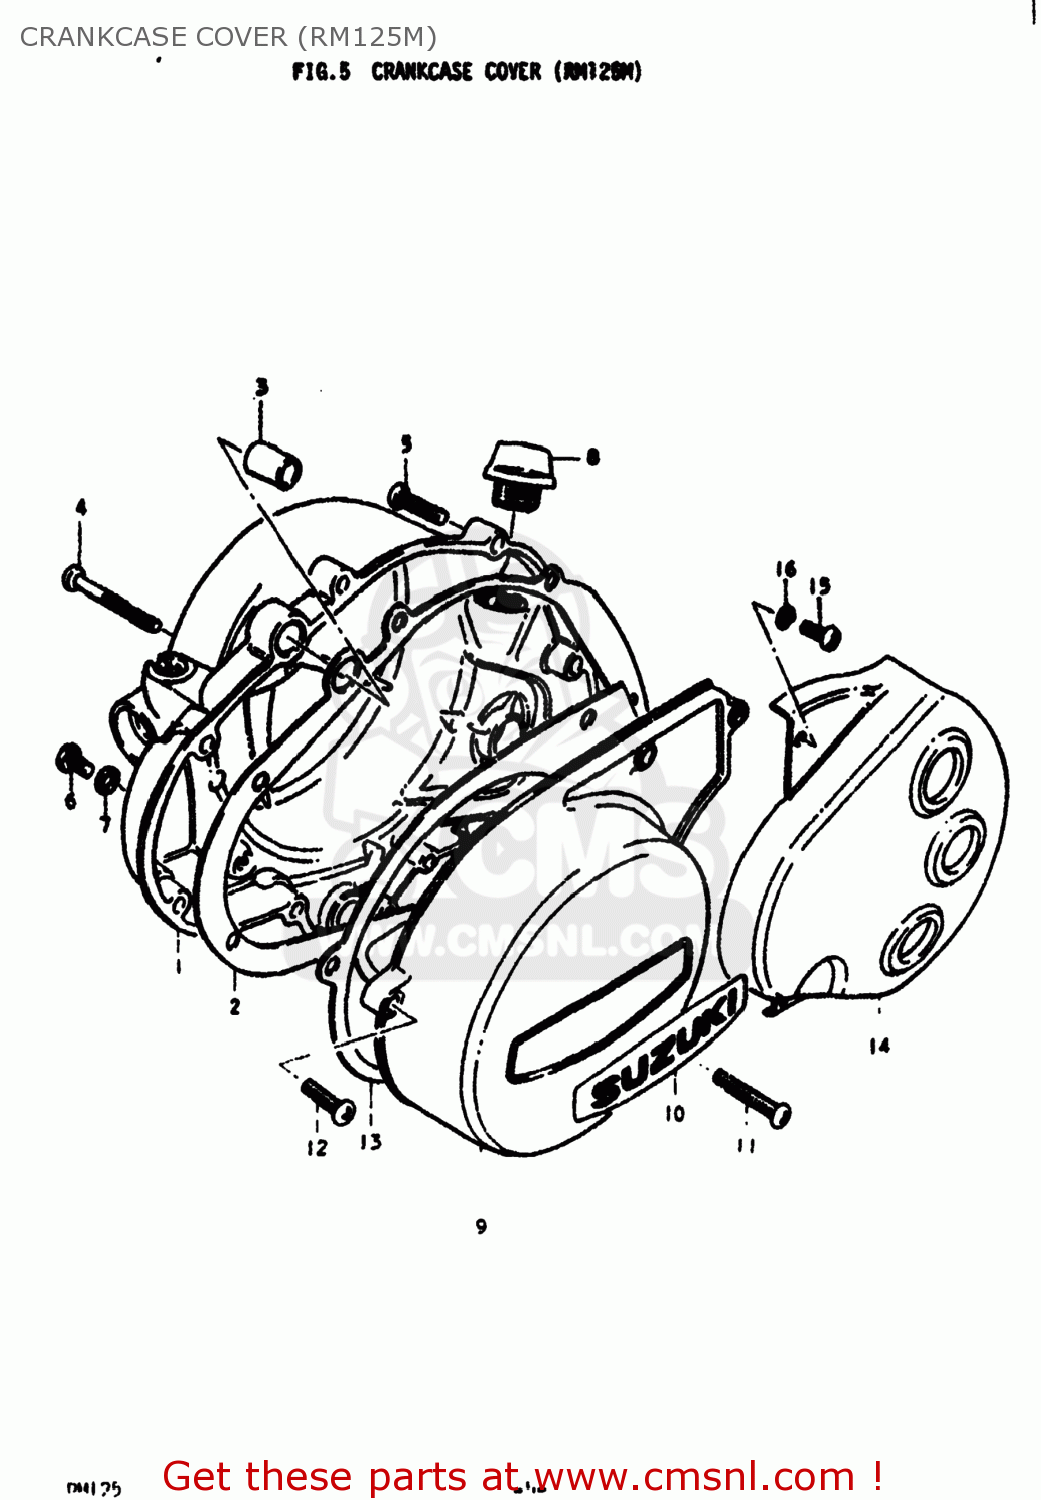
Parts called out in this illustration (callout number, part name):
1	CLUTCH COVER
2	GASKET,CLUTCH COVER (MCA)
3	PIN
4	SCREW (6X45)
5	SCREW
6	SCREW(6X10)
7	GASKET(6.2X11X1) (NAS)
8	PLUG,OIL FILTER
9	COVER
10	EMBLEM,MAGNETO COVER
11	SCREW
12	SCREW
13	GASKET,CLUTCH COVER (NAS)
14	COVER,ENGINE SPROCKET GLOSS
15	SCREW
16	LOCK WASHER
